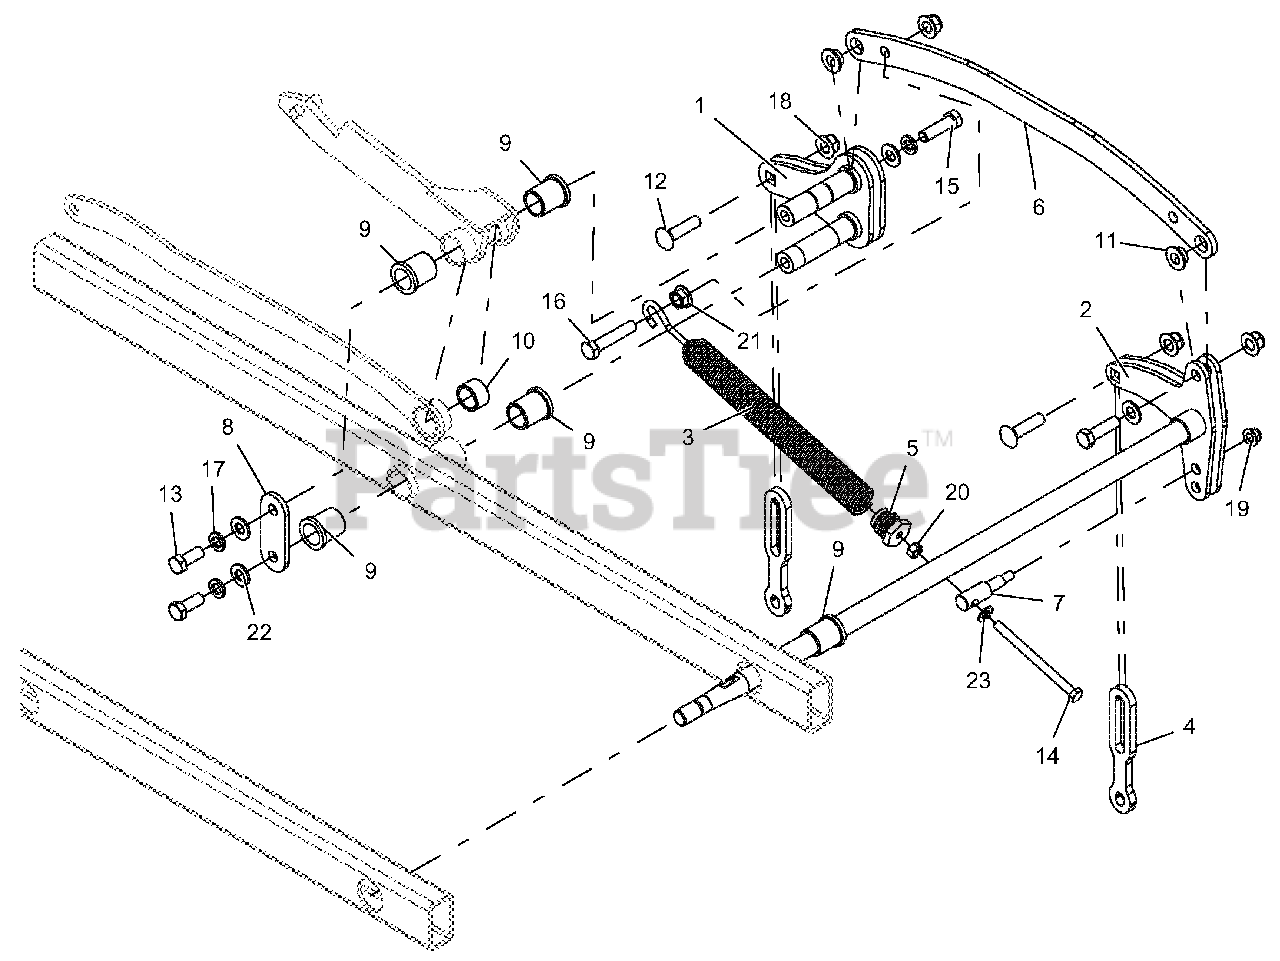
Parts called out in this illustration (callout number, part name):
1	WLDMT, DECK ARM
2	WLDMT, TAPERED SHAFT PROSTANCE (BLACK)
3	SPRG, DECK LIFT
4	LINK, DECK LIFT
5	PLUG, SPRG
6	ARM, DECK LIFT
7	TRUNION, DECK LIFT
8	PLATE, LIFT LINK ATTACH
9	BSHG-FLG 1.00 x 1.25 x 1.5 x 1.5
10	BSHG, 1.00 x 1.25 x .75
11	BSHG, FLANGE .515 x .750 x .420 x 1.12
12	BLT-RDHDSQNK .50-13 x 2.00 G5 Y
13	BLT-HEX .50-13 x 1.25 GR5 YWZC
14	BLT-HEX .38-16 x 5.00 GR5 YWZC
15	BLT-HEX .50-13 x 1.75 GR5 YWZC
16	BLT-HEX .50-13 x 2.50 GR5 YWZC
17	WSHR-LK .50 x .125 REG YWZC
18	NUT-LK-NYL-FLG .50-13 YWZC
19	NUT-LK-NYL-FLG .38-16 YWZC
20	NUT-HEX .38-16 YWZC
21	NUT .50-13 WIZ FLANGE
22	WSHR-FL-STL .531 x 1.06 x .095 YWZC
23	WSHR-FL-STL .406 x .812 x .065 YWZ
